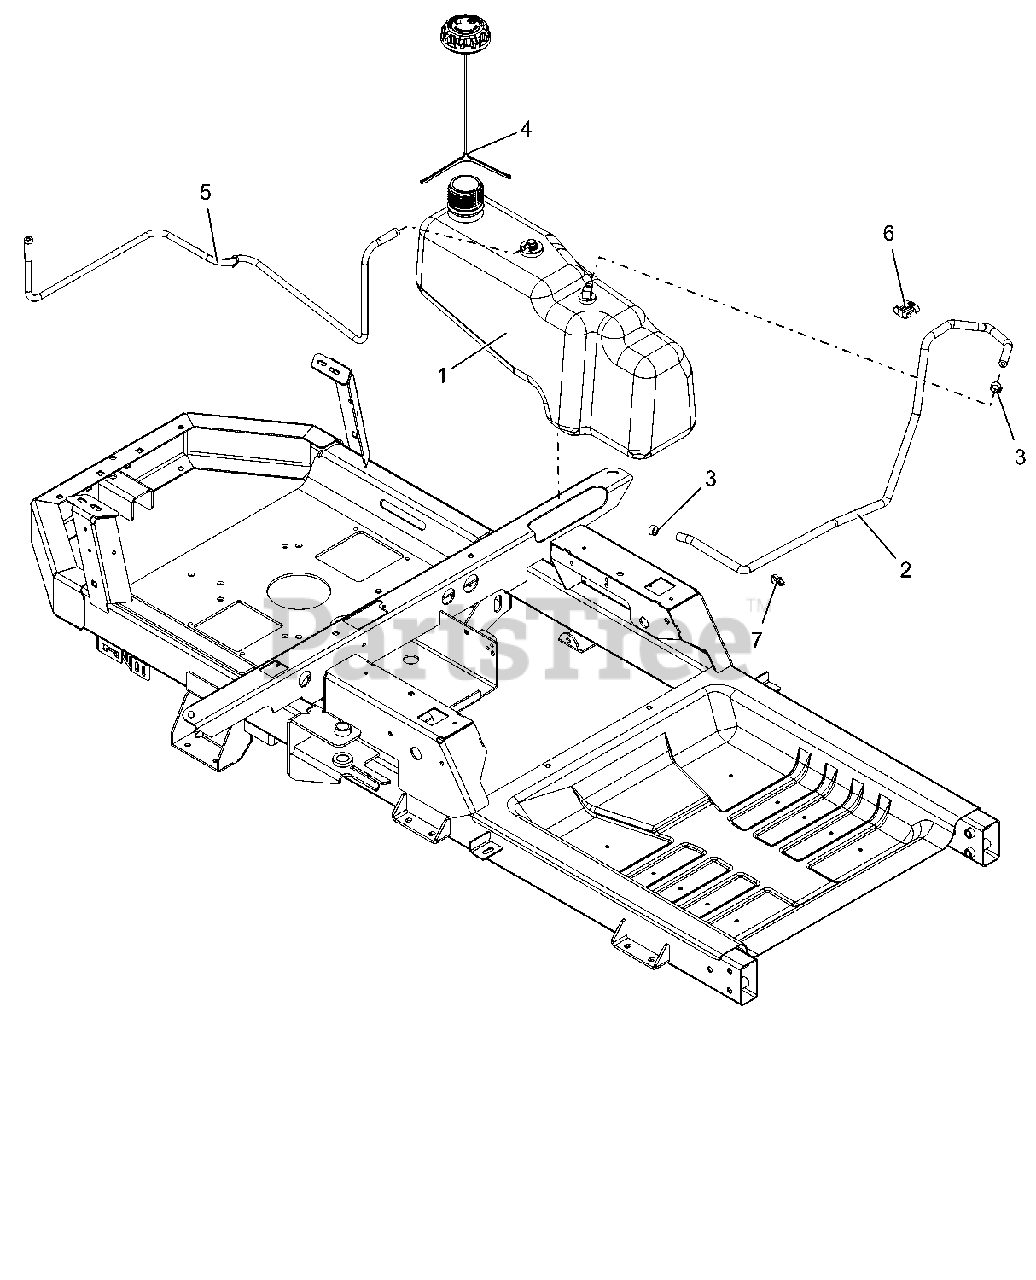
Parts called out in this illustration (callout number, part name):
1	ASM,TANK NON-PERM FUEL
2	HOSE, .25 LOW-PERM BULK GAS
3	CLAMP, FUEL LINE
4	CAP, FUEL VENT-IN 2.25" RATCH.
5	LINE, FUEL VENT KOHLER
6	CLIP, T, .38-.50
7	ROUTING CLIP (1/2" ID)
